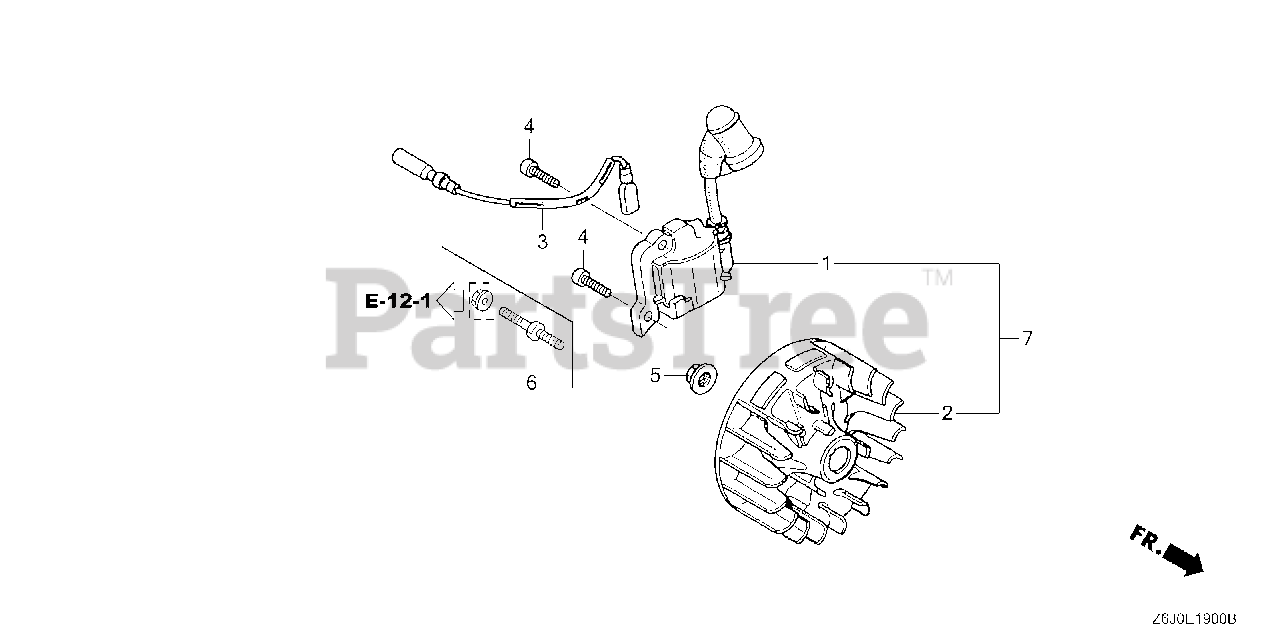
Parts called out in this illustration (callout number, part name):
1	COIL ASSY., IGNITION
3	WIRE, STOP SWITCH
4	BOLT, SOCKET (4X14)
5	NUT, FLANGE (7MM)
